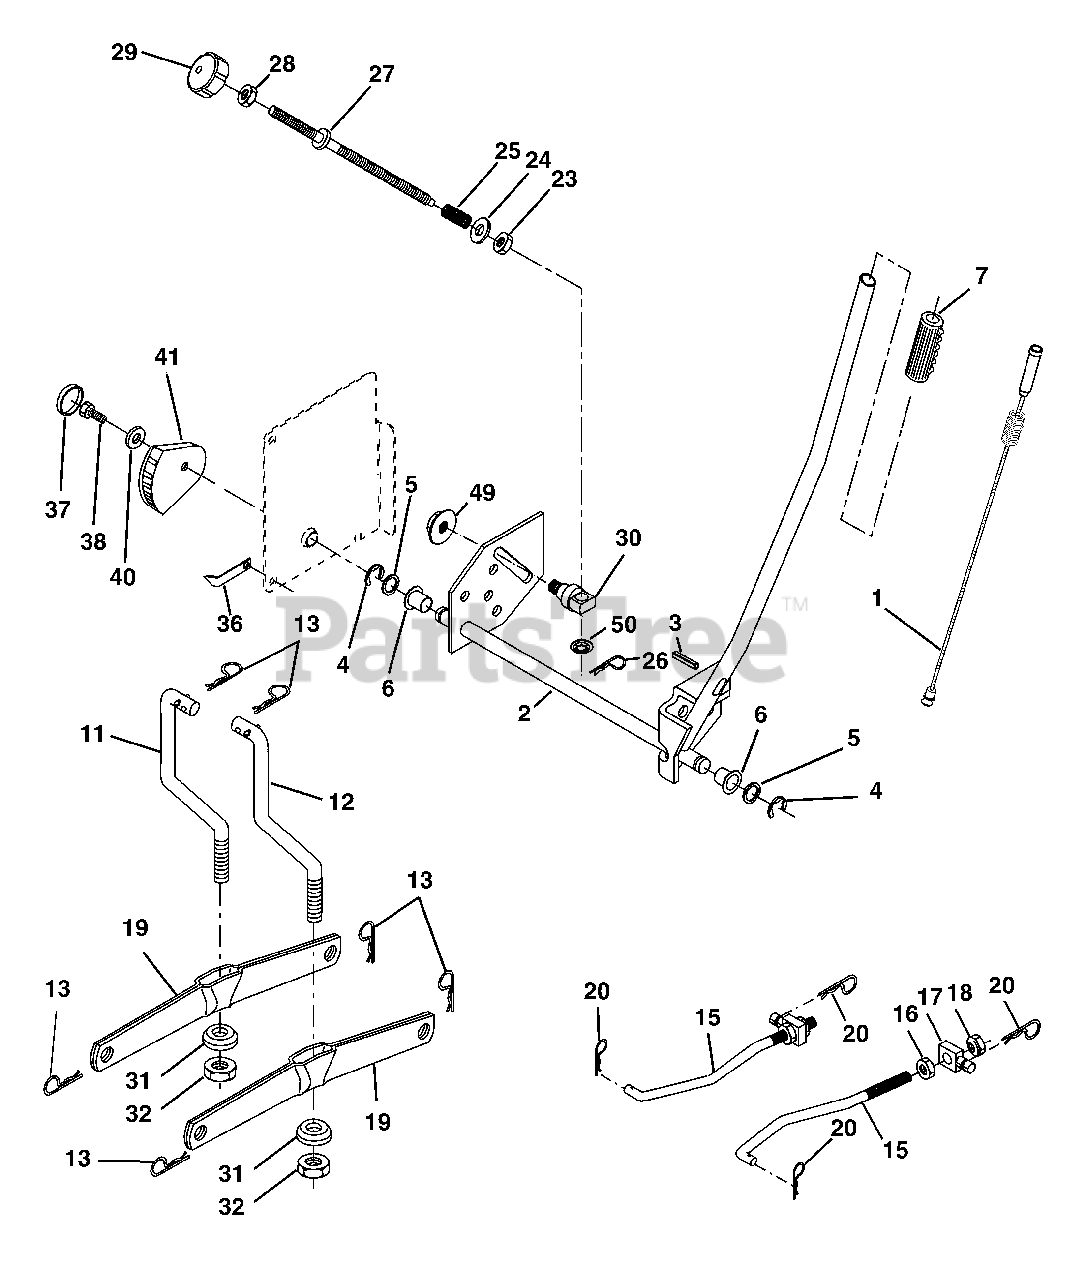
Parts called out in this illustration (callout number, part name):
1	Plunger Asm.
2	Shaft Asm Lift
3	Pin Groove
4	E Ring #5133-62
5	Washer 21/32 x 1 x 21 Ga.
6	Bearing Nylon
7	Grip Handle
11	Link Lift Lh
12	Link Lift Rh
13	Retainer Spring
15	Link Front
16	Nut Jam Hex 1/2-13 Unc
17	Trunnion Blk Zinc
18	Nut Lock w/Wsh 1/2-13 Unc
19	Arm Suspension Rear
20	Retainer Spring
23	Nut Special
24	Washer 13/32 x 5/8 x 16 Ga.
25	Spring
26	Retainer Clip
27	Rod Adj. Lift
28	Nut Hex Jam 3/8-16 Unc
29	Knob
30	Trunnion Infin. Height
31	Bearing Pvt Lift
32	Nut Crownlock 3/8-24
36	Pointer Height Indicator
37	Plug Hole
38	Screw 5/16-18 x 1
40	Washer 11/32 x 1-1/2 10 Ga.
41	Indicator Height
49	Nut Hex Flange Lock
50	Nut Push
